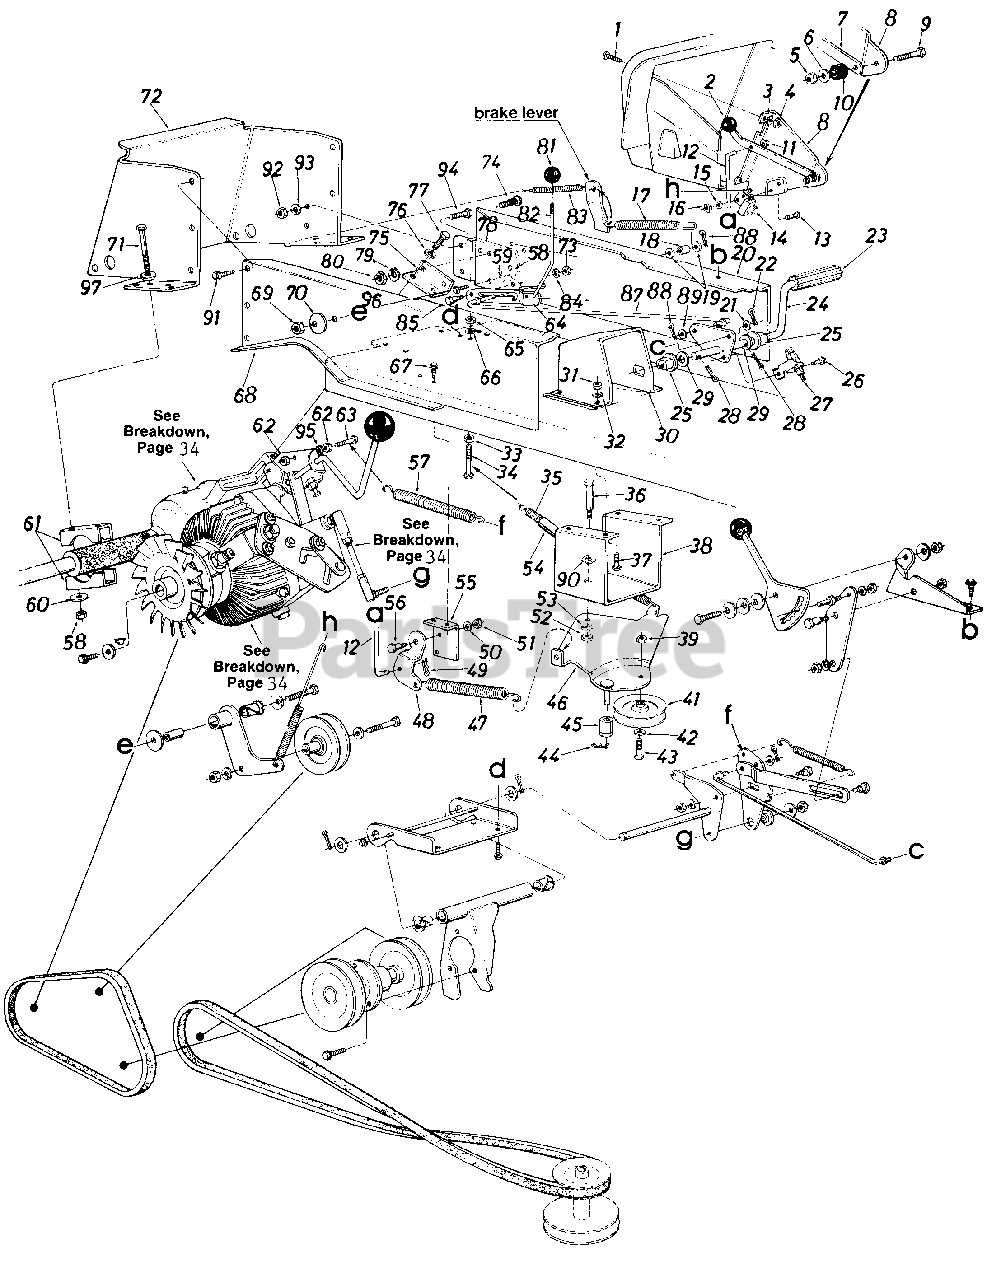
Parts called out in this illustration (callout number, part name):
1	Truss Mach. Scr. 1/4-20 x .50" Lg.
2	Knob-Blade Clutch
4	Hex Sems Nut 1/4-20 Thd.
5	Hex Cent. L-Nut 1/4-20 Thd.
6	Fl-Wash. 1/4" I.D. x .75" O.D.
7	PTO Lever
8	Deck Clutch Control Brkt.
9	Hex Bolt 1/4-20 x .75" Lg.*
10	Rubber Wash. .33" I.D. x .87" O.D.
11	Push Cap /4/1 Rod
12	Deck Control Rod
13	Truss Mach. Scr. #10-24 x .50" Lg.
14	Safety Switch
15	Ext. L-Wash. #10 Scr.
16	Hex Nut #10-24 Thd.
17	Extension Spring .75" O.D. x 5.56" Lg.
18	Spacer .375" I.D. x .625" O.D. x .445" Lg.
19	Fl-Wash. .385" I.D. x .87"O.D.
20	Side Panel Upper Frame-LH.
21	Fl-Wash. .385" I.D. x .87" O.D.
22	Cotter Pin 3/32" Dia. x .75"
23	Foot Pad
24	Foot Pedal Brkt. Ass'y.
25	Flange Brg. .630" I.D. x 1.25" O.D.
26	Hex Wash. Hd. S-Tap Scr. 1/4-20 x .50" Lg.
27	Safety Switch
28	Cotter Pin 118" Dia. x 1.00"
29	Fl-Wash. .640" I.D. x .24" O.D.
30	Steering Gear Support Ass'y.
31	Fl-Wash. .385" I.D. x .87" O.D.
32	L-Wash. 5/16" I.D.
33	Hex Nut 1/4-20 Thd.
34	Hex Bolt 1/4-20 x 2.0" Lg.
35	Extension Spring .50" O.D. x 6.37" Lg.
36	Shld. Bolt 7/16" Dia. x .16"
37	Hex Bolt 5/16-18 x 1.00"*
38	Idler Mtg. Brkt.-Deck
39	Hex L-Nut 3/8-16 Thd.
41	"V"-Idler Pulley
42	Fl-Wash. 3/8" I.D.
43	Hex Bolt 3/8-16 x 1.75" Lg.
44	Cotter Pin 5/16" Rod
45	Spacer
46	Idler Brkt. Ass'y.
47	Extension Spring-Deck Control
48	Deck Control Pivot Brkt.
49	Cotter Pin 5/16" Rod
50	L-Wash. 5/16" I.D.*
51	Hex Nut 5/16-18 Thd.
52	Hex Nut 5/16-18 Thd.
53	L-Wash. 5/16" I.D.
54	Convoluted Conduit .50" I.D. x 4" Lg.
55	Parking Brake Cam Mtg. Brkt.
56	Shld. Bolt 7/16" Dia. x .16"
57	Extension Spring
58	Hex Nut 3/8-16 Thd.
59	L-Wash. 3/8" I.D.
60	Bell-Wash .39" I.D. x 1.13'
61	Rear Axle Brkt.
62	Hex Nut 5/16-24 Thd.
63	Hex Scr. 5/16-24 x 1.5"
64	Parking Brake Cam
65	Hex Nut 1/4-20 Thd.
66	L-Wash. 1/4" I.D.
67	Hex Wash. Hd. S-Tap Scr. 1/4-20 x .50" Lg.
68	Side Panel Upper Frame-R.H.
69	Hex Nut 3/8-24 Thd.
70	Fl-Wash. .39" I.D. x 1.5" O.D.
71	Hex Bolt 3/8-16 x 3.50" Lg.
72	Hitch Plate
73	Hex Nut 3/8-16 Thd.
74	Rd. Hd. Ribbed Neck Bolt 3/8-24 x 1.0" Lg.
75	Mounting Brkt. Transaxle
76	L-Wash. 3/8" I.D.
77	Hex Bolt 3/8-16 x 1.00" Lg. (Grade 5)
78	Reinforcement Plate-Frame
79	L-Wash. 3/8" I.D.
80	Hex Nut 3/8-24 Thd.
81	Gear Shift Knob
82	Parking Brake Link
83	Extension Spring .38" O.D. x 3.18" Lg.
84	Hex Nut 3/8-16 Thd.
85	Shld. Bolt .500" Dia. x .170
87	Rod-Brake .38" Dia. x 1 9.3" Lg.
88	Cotter Pin 3/32" Dia. x .75"
89	Fl-Wash. .385" I.D. x .87"
90	Wave Wash.
91	Hex AB-Tap Scr. 5/16 x .75"
92	Hex Nut 5/16-24 Thd.*
93	L-Wash. 5/16" I.D.
94	Hex Bolt 5/16-24 x .75" Lg.
95	L-Wash. 5/16" I.D.
96	Hex Bolt 3/8-16 x .75" Lg.
97	Fl-Wash. .385" I.D. x .870" O.D.
